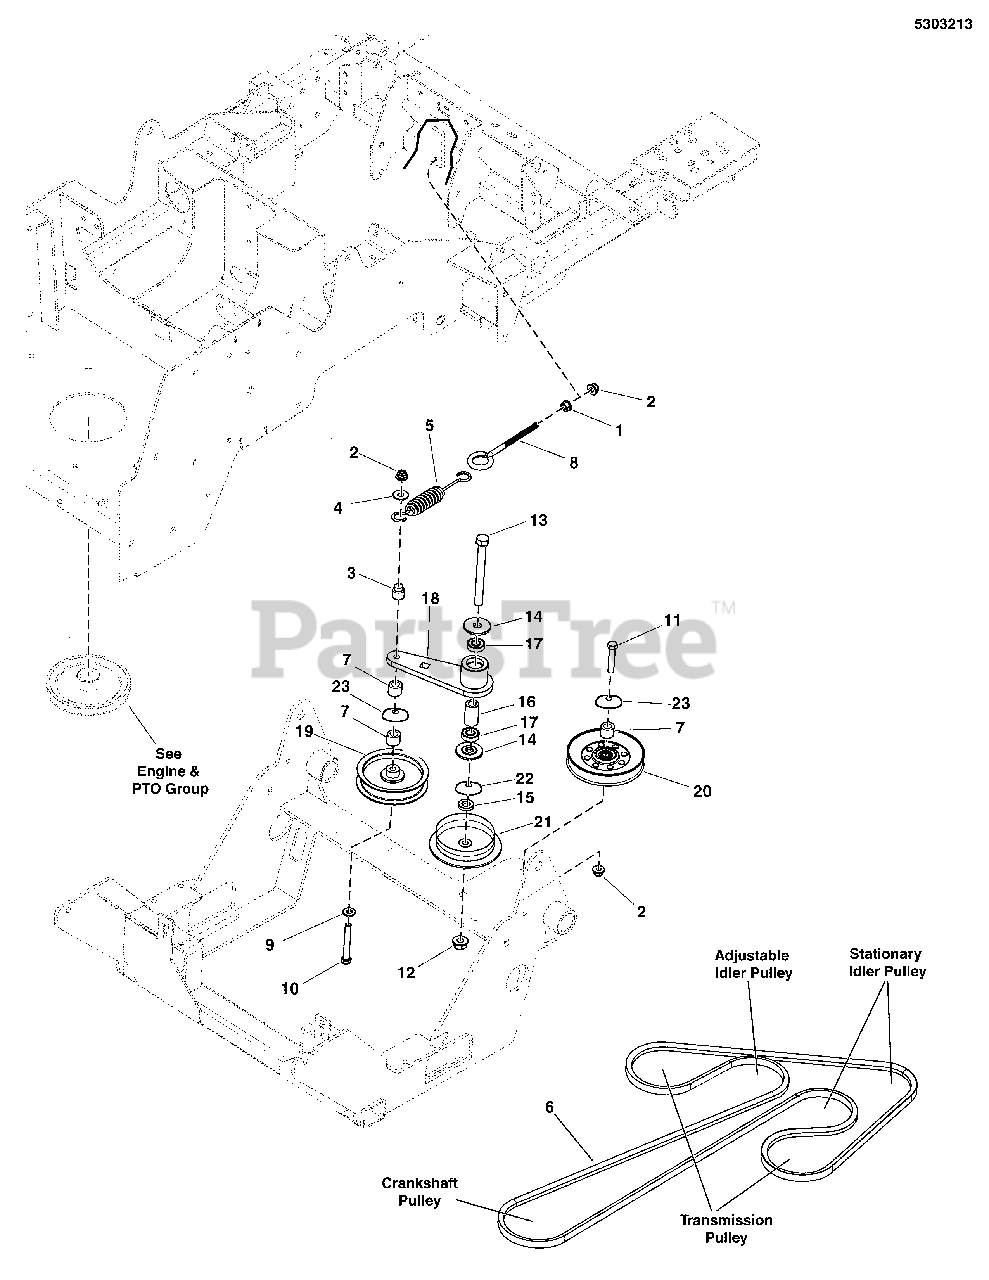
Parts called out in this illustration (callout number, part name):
1	NUT, 3/8-16 HEX SERRATED FLANGE
2	NUT, 3/8-16 HEX NYLOCK FLANGE
3	SPACER, SHOULDER
4	WASHER, 3/8 USS
5	SPRING-EXT, 1.25OD X 9.3LG X .142WR, BLK
6	BELT, A-SEC, 117.24"EL, WRAPPED, ARAMID
7	SPACER, .39 X 1.00 X .25
8	EYE BOLT, 3/8-16 X 5,2.88THRD, 1 EYE
9	WASHER 3/8" GD9
10	BOLT, 3/8-16 X 3 GD5 YZ
11	BOLT, 3/8-16 X 2-1/4 GD5 YZ
12	NUT, 1/2-13 HEX NYLOCK FLANGE
13	BOLT-1/2-13 X 5 GD5 YZ
14	SPACER, IDLER ARM, 1/2"
15	SPACER, .52 X 1.00 X .22, CZ
16	SPACER, .52 X .84 X 1.53, PM
17	BEARING, BALL, AXLE
18	WELD, ARM, PUMP DRIVE IDLER - BLK
19	PULLEY, IDLER-V, 4.0 X .38, STL
20	PULLEY-IDLER-V, 4.85OB, .38ID, .94W,STL
21	PULLEY, IDLER, SINGLE FLG 4"OD X 1/2"ID
22	SHIELD, PULLEY BEARING
23	SHIELD, BEARING PULLEY, 3/8ID
